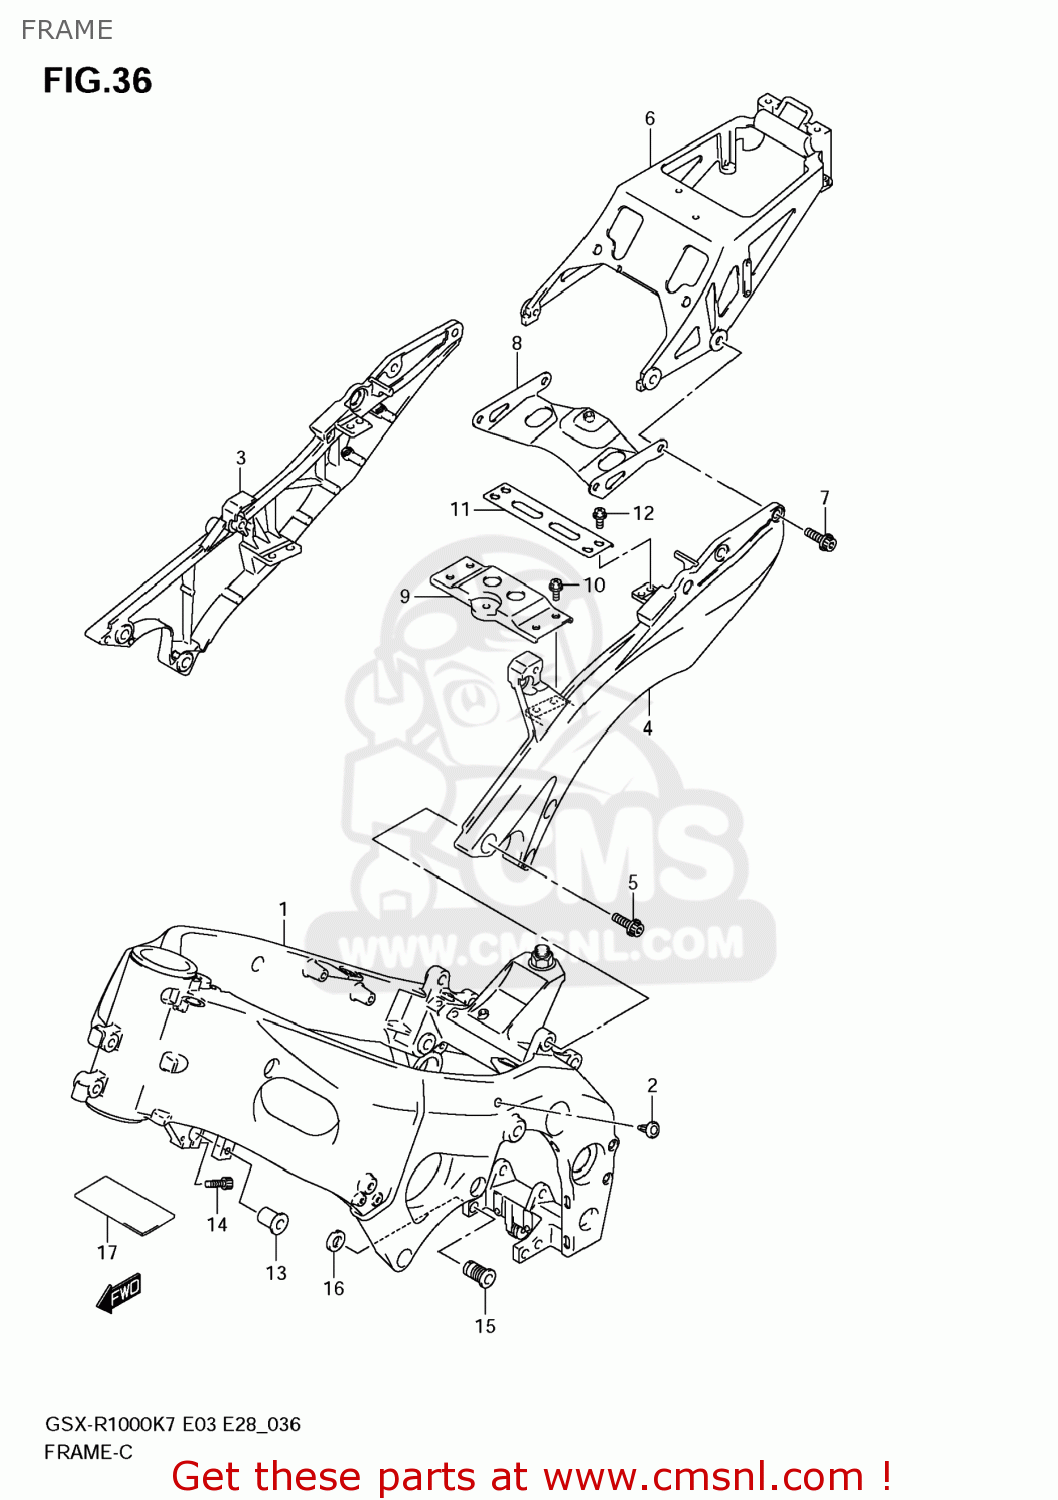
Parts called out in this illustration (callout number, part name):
1	FRAME(BLACK)
2	PLUG,TANK RAIL
3	RAIL,SEAT,R(BLACK)
4	RAIL,SEAT,L(BLACK)
5	BOLT,SEAT RAIL
6	BRACKET,PILLION SEAT
7	BOLT
8	BRIDGE,SEAT RAIL RR
9	BRIDGE,SEAT RAIL FR
10	BOLT(6X12)
11	BRIDGE,SEAT RAIL UPR
12	BOLT(6X12)
13	SPACER,ENGINE MOUNTING
14	BOLT(8X32)
15	BOLT,CRANK CASE ADJUST
16	NUT,ADJUST BOLT
17	CUSHION,FRAME HEAD
